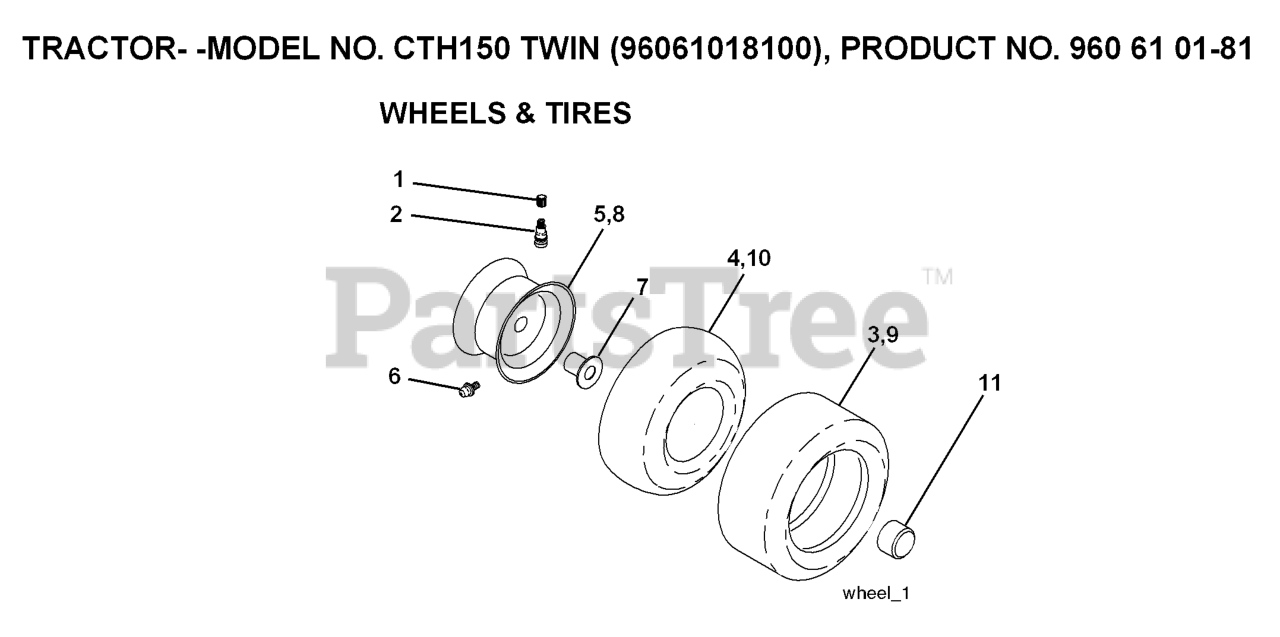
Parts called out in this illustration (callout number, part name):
2	VALVE STEM LT
3	TIRE HEAVY DUTY
4	TUBE.5.3/4.5/6
5	RIM ASM 6" FRONT SILVER
6	FITTING LT
7	BEARING T
8	RIM ASM 8" REAR SILVER
9	TIRE.TS.20X10-8
10	TUBE
11	CAP, AXLE BLK
